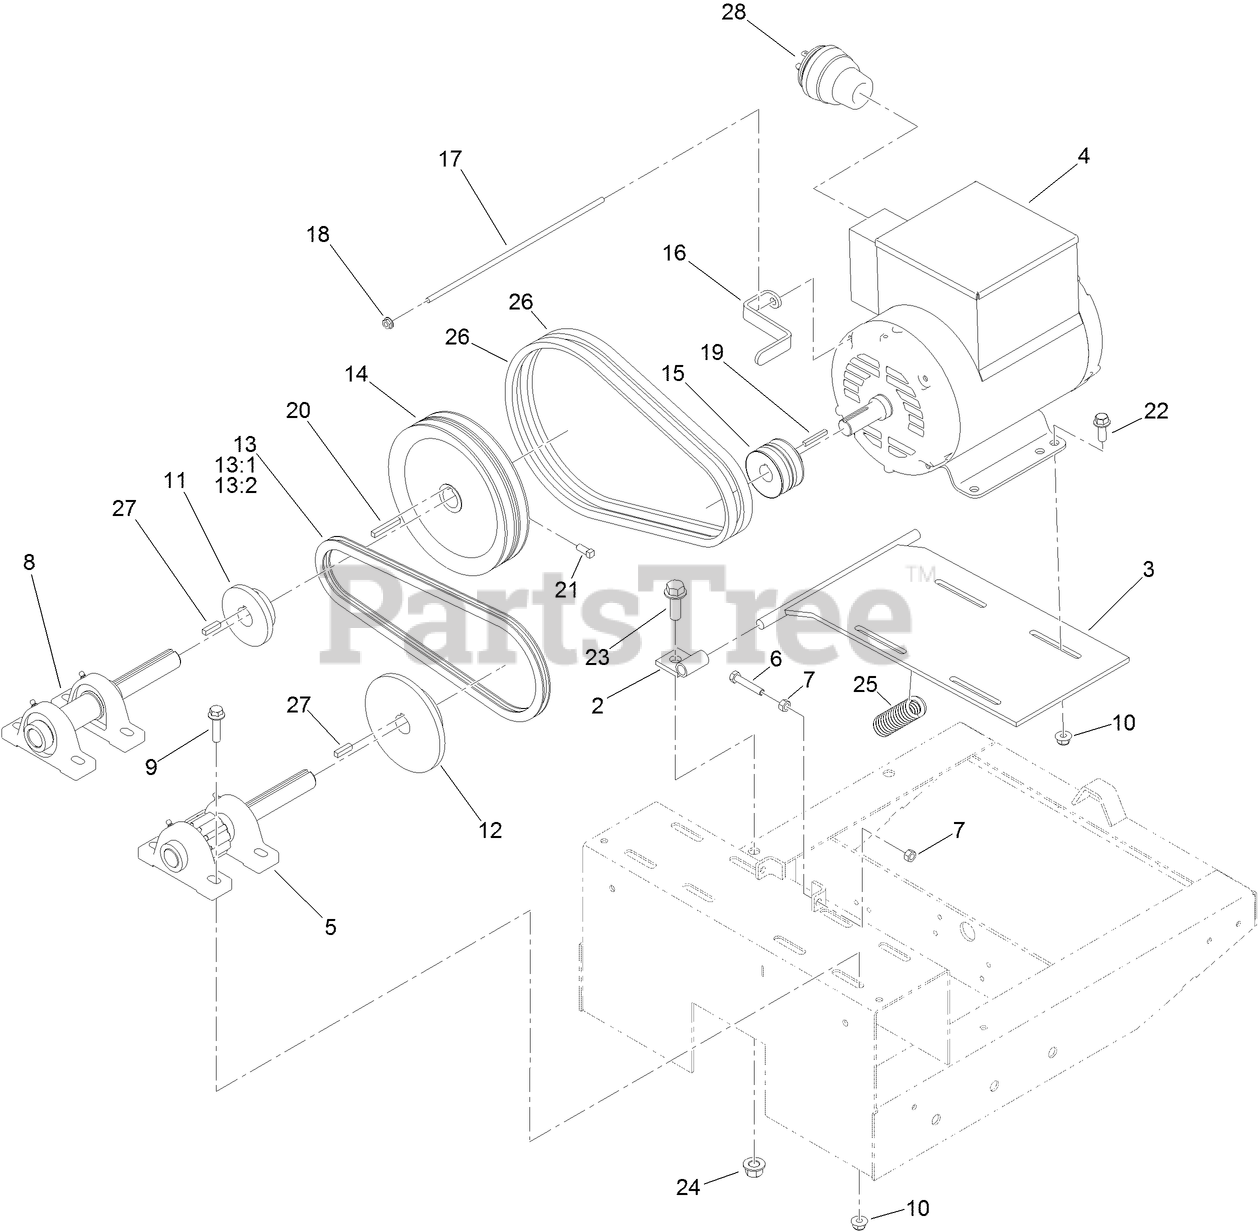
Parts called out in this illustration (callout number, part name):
2	MOUNT-MOTOR
3	BASE-MOTOR
4	MOTOR-ELECTRIC
5	PINION ASM
6	SCREW-HH
7	NUT-HEX
8	IDLER ASM
9	SCREW-HHF
10	NUT-HF, NI
11	SPROCKET
12	SPROCKET
13	CHAIN SET
13:1	CHAIN
13:2	LINK-CONNECTING, NO. 50
14	SHEAVE
15	SHEAVE
16	GUIDE-BELT
17	ROD-THREADED
18	NUT-HF
19	KEY-SQUARE
20	KEY-SQUARE
21	SCREW-SET, SQH
22	SCREW-HHF
23	SCREW-HHF
24	NUT-LOCK
25	SPRING
26	BELT-V
